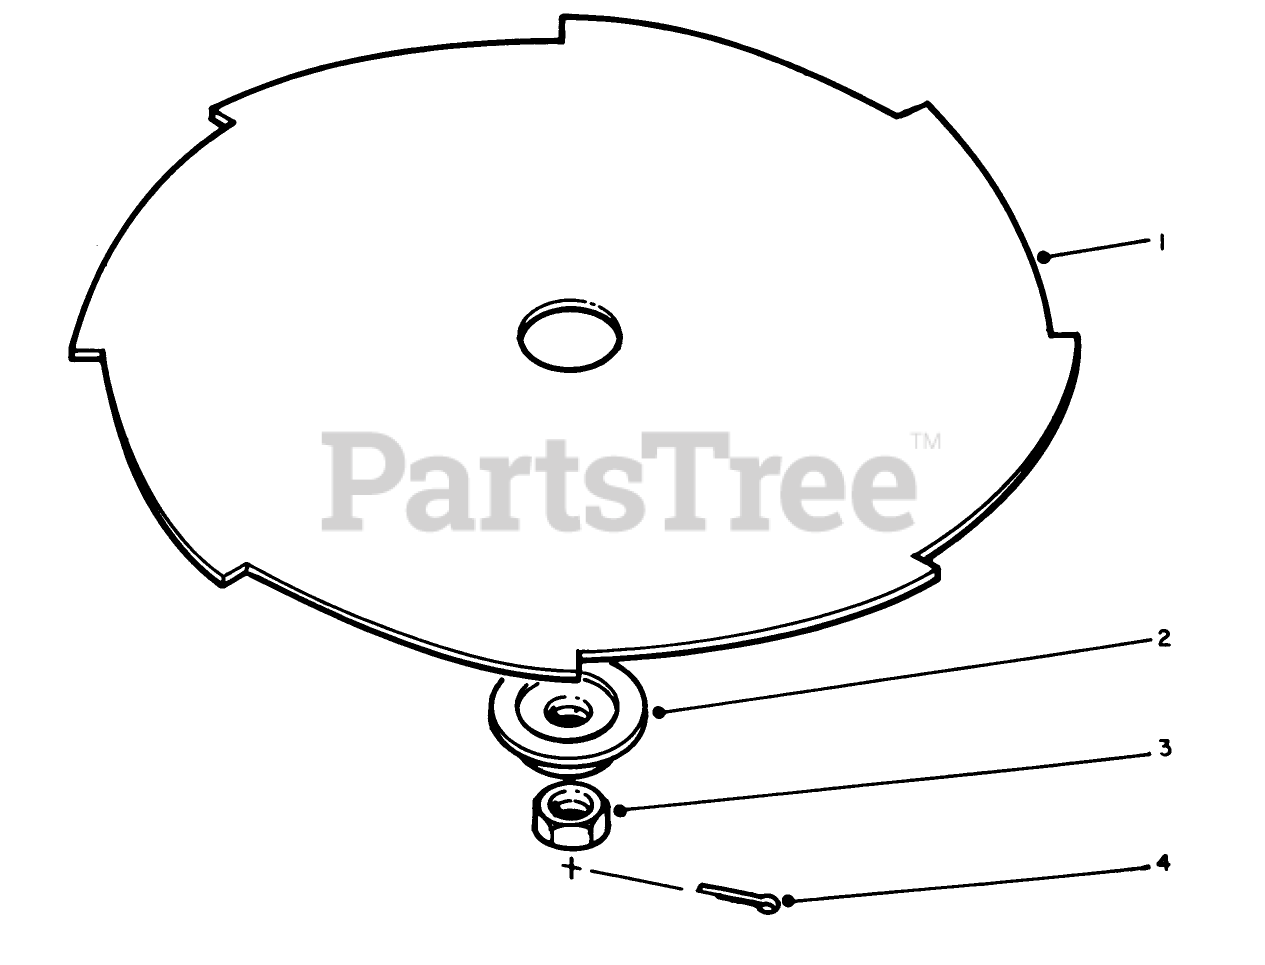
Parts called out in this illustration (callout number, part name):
1	BRUSH BLD PKG(8",8T)
2	Adapter-Blade
4	1/16 X 1 LG COTTER PIN
